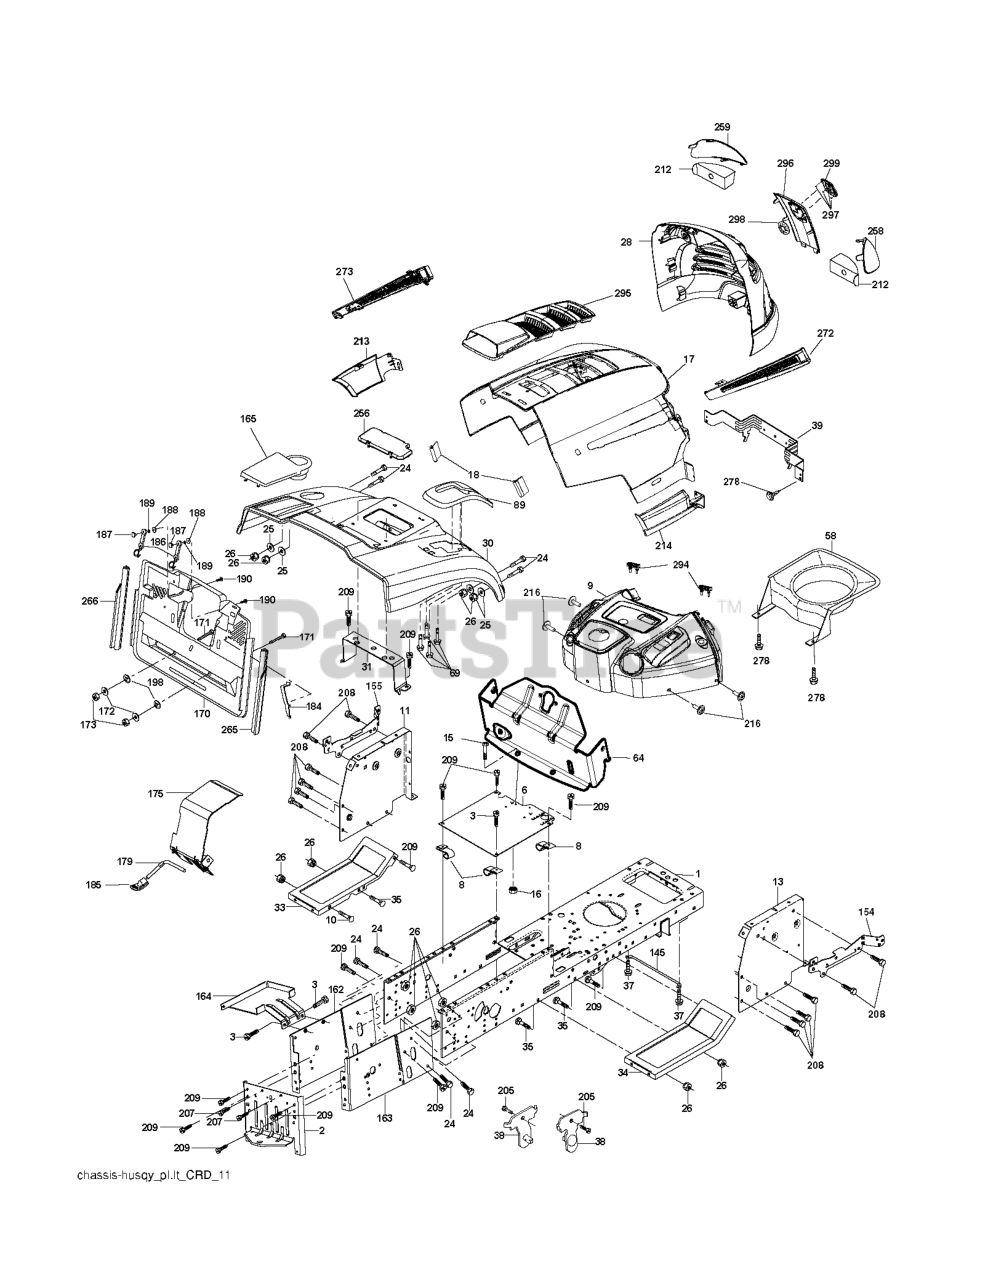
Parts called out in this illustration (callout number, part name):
2	DRAWBAR
3	SCREW 3/8-16X3/4
6	PLATE
8	CLIP,INSULATOR
10	BOLT D
11	PANEL.DASH.LH.LTX
13	PANEL ASM, DASH RH
15	Screw, Machine, Truss Head 5/16-18 UNC x 3/4
16	NUT
17	HOOD
18	BUMPER.HOOD.TEX.HUSQVARNA
24	BOLT
25	WASHER
26	NUT
28	RP GRILLE/LENS ASM.
30	CONSOLE.CRD.AUTO.GRY
31	BRACKET SUPPORT FENDER
33	FOOTREST PNT LH
34	FOOTREST PNT RH
35	BOLT
37	Screw 5/16-18 x 1/2 Hex, Self Tapping 5/16-18 x 1/2
38	BRACKET ASM PIVOT MOWER REAR
39	BRACKET PIVOT
69	SCREW.HI-LO.CONSOLE
145	ROD.PIVOT.HOOD
162	BRACKET
163	BRACKET EXTEN CHASSIS RH CRD
165	RP.COVER.BATTERY.CRD.GREY
171	BOLT
172	WASHER
175	DOOR TRAP
179	ROD PIVOT FBI
184	BRACKET.ACTUATOR.BAGGER.SRD
186	LATCH ASSY
187	WELDNUT
189	LOCKWASHER #10
190	SCREW
205	SCREW LT
207	SCREW, 5/16-18 X 1/2
208	SCREW 3/8-16X1/2
209	SCREW, 3/8-16X3/4
212	INSERT REFLECTIVE
213	SKIRT SIDE LH
214	SKIRT SIDE RH
216	SCREW HEXWSHR 1/4-20X3/4
256	COVER FENDER CRD
258	LENS.HUSQVARNA LT.RH
259	LENS.HUSQVARNA LT.LH
265	SEALING
266	SEALING
272	VENT SIDE HOOD RH
273	VENT SIDE HOOD LH
278	SCREW
294	BUMPER DASH
295	VENT TOP HOOD
296	TRIM
297	CLIP.RETAINER.TINNER.
298	NUT PUSH M
299	RP LOGO
